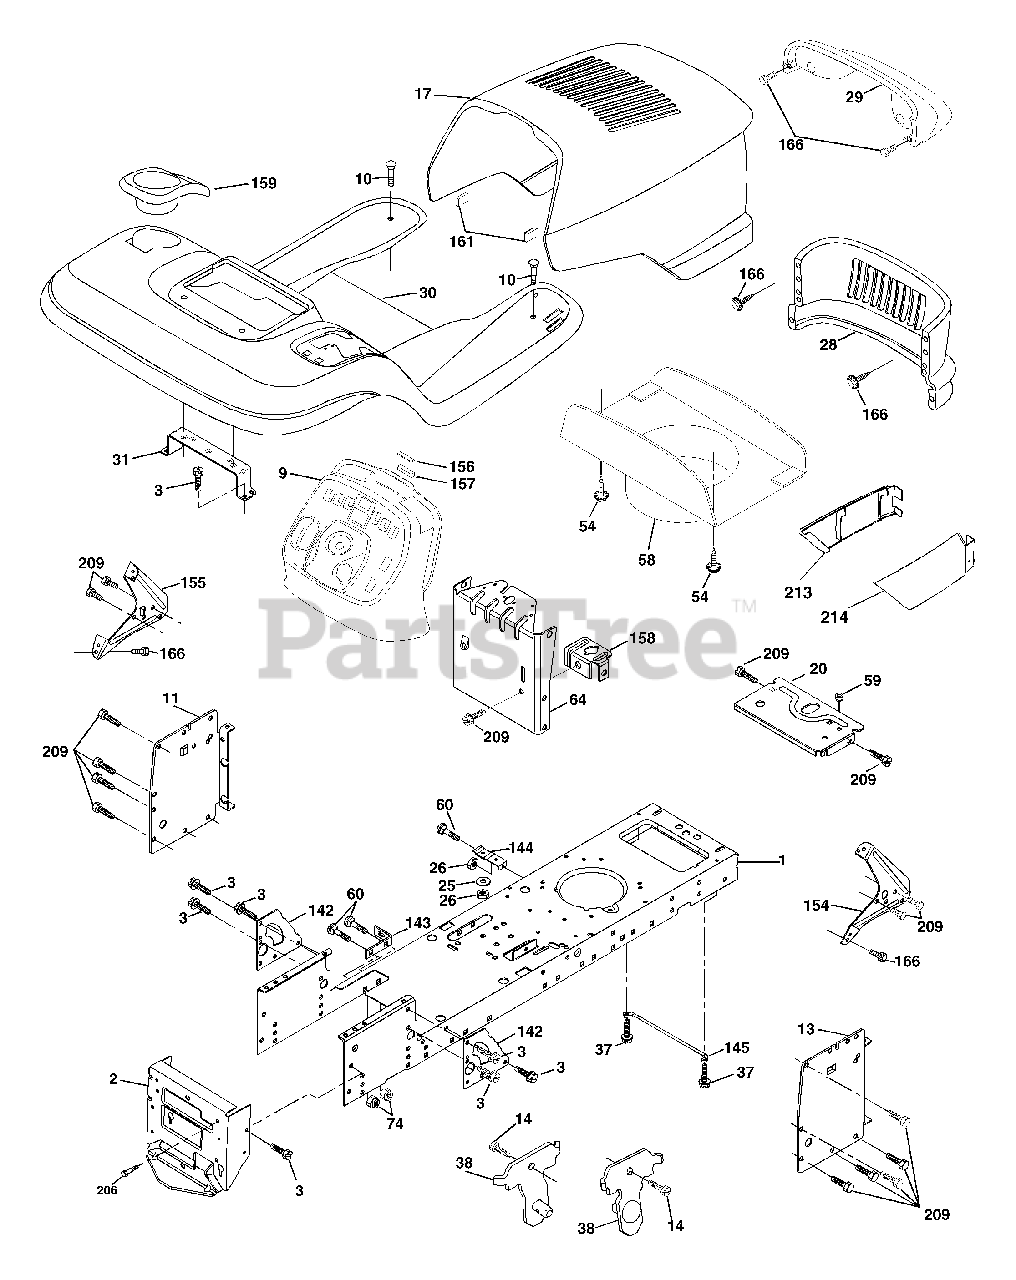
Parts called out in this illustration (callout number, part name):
1	Chassis
2	Drawbar
3	Screw 3/8-16x3/4
9	Dash
10	Bolt 3/8-16 x 1
11	Panel Dash Lh
13	Panel Dash Rh
14	Screw Thdrol 3/8-16 x 1/2
17	Hood
20	Plate Battery
25	Washer 13/32 X 13/16 X 12 Ga
26	Nut Lock Hex W/Ins 3/8-16 Unc
28	Grille
29	Lens
31	Bracket Fender
37	Screw Thdrol 6/16-18 x 1/2 TYT
38	Bracket, Asm. Pivot Mower Rear
54	Screw Hex Wshd 8-18 x 7/8
58	Duct Hood
59	Bushing Snap
60	Bolt Rd Hd Sqnk 3/8-16 Unc x 3/4
64	Dash Lower
74	Nut Crownlock 3/8-16 Unc
142	Plate Reinforcement STLT
143	Bracket Swaybar Chassis
144	Bracket Footrest
145	Rod Pivot Chassis/Hood
154	Bracket Dash Rh
155	Bracket Dash Lh
156	Striker Plate
157	Magnet Stealth
158	Bracket Parking Brake
159	Cupholder
161	Extrusion Bumper
166	Screw Hw Hd Hi-Lo #13-16 x 3/4
206	Bolt Shoulder 5/16-18
209	Screw Hexwsh Thdrol 3/8-16 x 3/4
213	Skirt Grille Lh
214	Skirt Grille Rh
